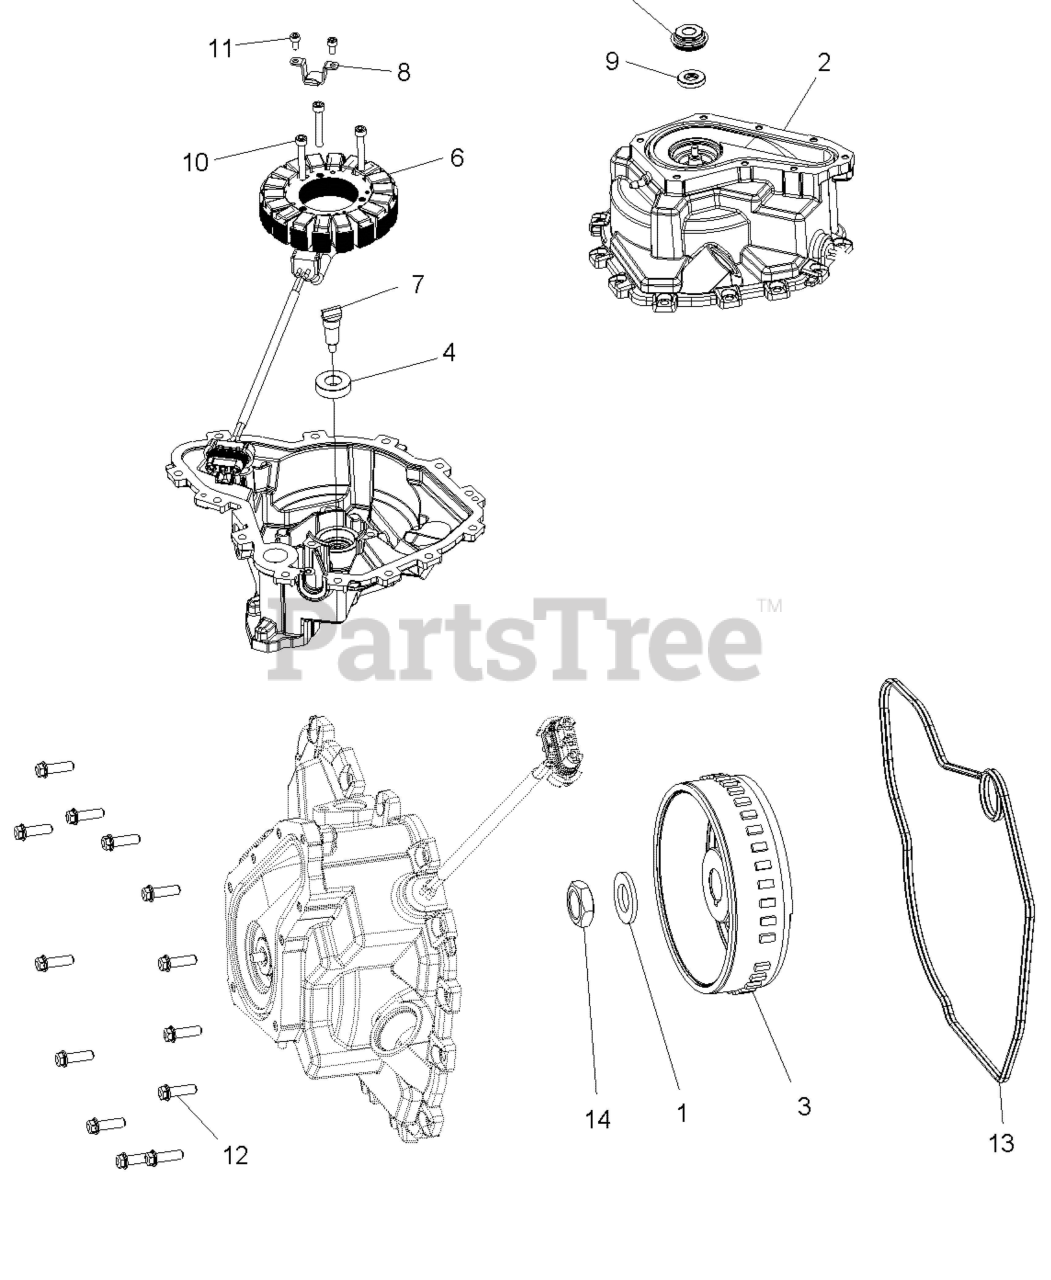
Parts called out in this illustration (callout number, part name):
2	ASM,SPRAG CLUTCH,HUB,STARTER
3	FLYWHEEL
4	BEARING-SHAFT,WATERPUMP
5	SEAL-WATERPUMP SHAFT,WATER
6	STATOR-660W
7	SHAFT-PUMP DRIVE,G-1CYL
8	GUIDE-STATOR LEAD
9	SEAL,TYPE S,ARS
10	SCR-M6X1.0X40,HX/SOC/CP-Y/D
11	SCR-M5X0.8X10 SOC/CP-D
12	SCR-M6X20,HXFLG,0600214
13	GASKET-STATOR COVER
14	NUT-HEX,M18X1.5 4 JAM,RH
